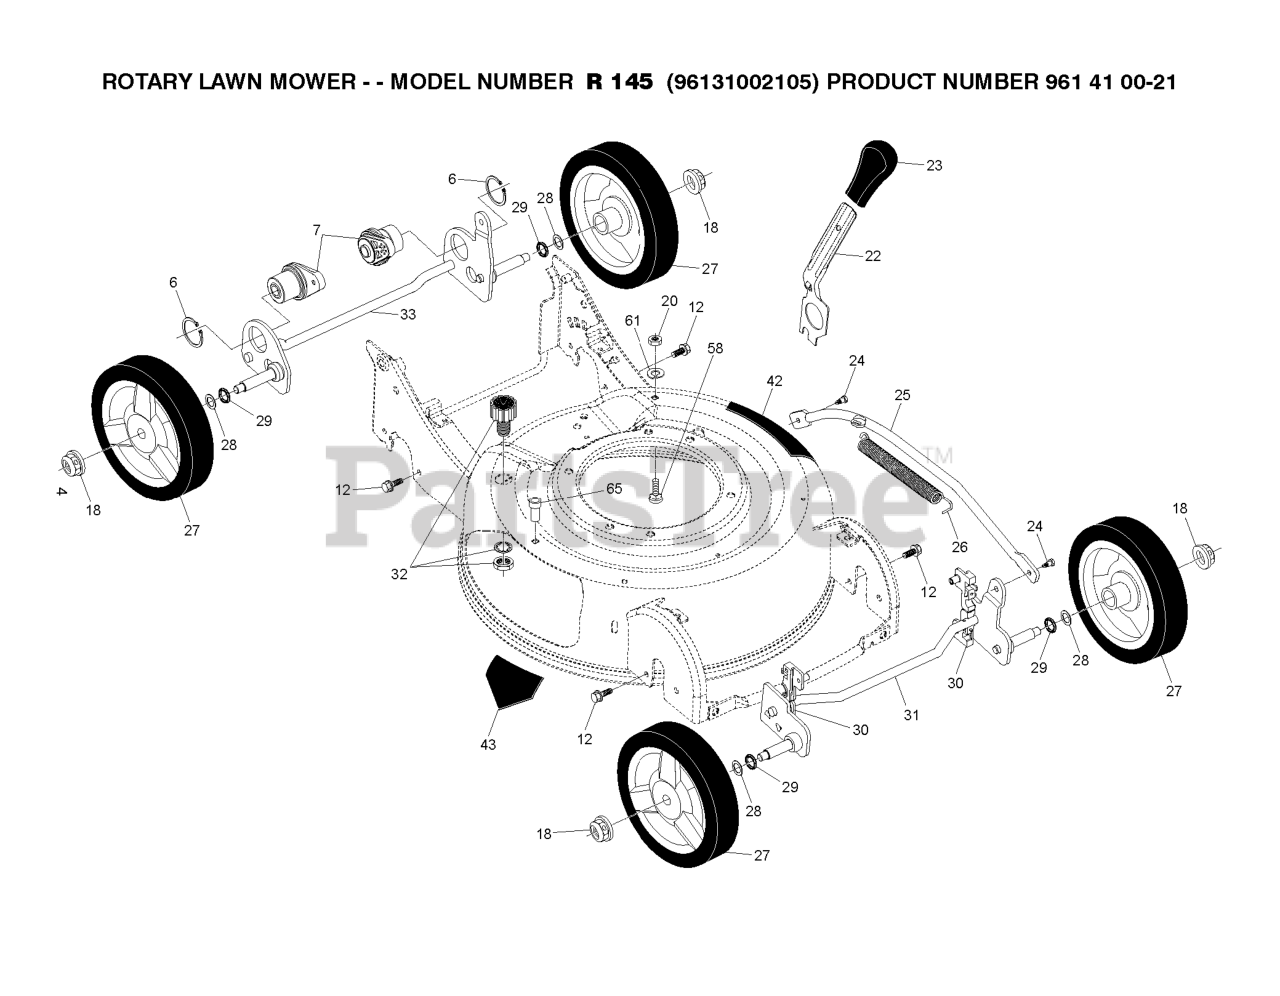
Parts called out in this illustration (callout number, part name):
6	RETAINING RING (2 2)(3 2)
18	NUT.HEX.FLANGE.3/8-16.LO(3 2)
20	NUT, HEX
24	SHOULDER BOLT SEMI GIMLET PT.
25	ROD.LIFT.BZP
26	SPRING EXTENSION
27	WHEEL & TIRES ASSY, FRONT
28	WASHER.FLAT.1/2
29	O-RING..070X.487.NEOPRENE
30	BUSHING.FRONT.TORQUE.S
33	AXLE.ASM.REAR.TORQUE.BZP
43	DECAL.INTERNATIONL.CUTFINGER
58	BOLT.CARRIAGE.1/4-20 X 7/8
61	LOCKWASHER
